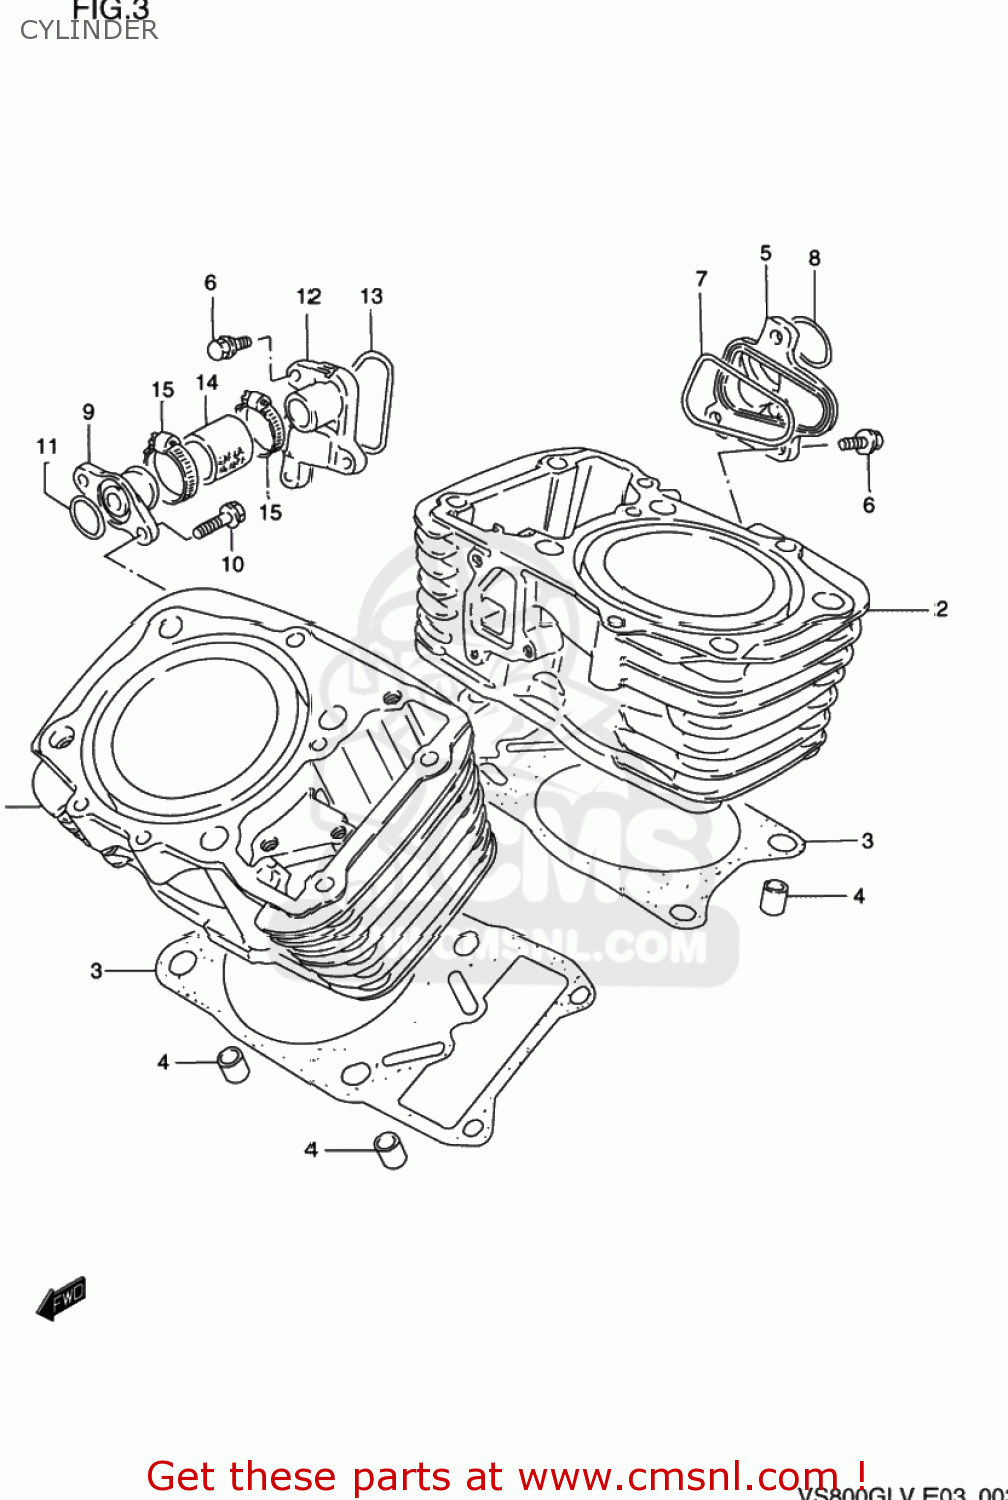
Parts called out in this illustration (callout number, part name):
1	CYLINDER,FR
2	CYLINDER
3	GASKET,CYLINDER (NAS)
4	PIN
5	CHAMBER,WATER,INLET
6	BOLT
7	O RING,INLET WATER CHAMBER
8	O RING(D:2.3,ID:24.4)
9	UNION,WATER INLET
10	BOLT
11	O RING(D:2.4,ID:15.8)
12	CHAMBER,WATER,OUTLET
13	O RING,OUTLET WATER CHAMBER
14	HOSE,RADIATOR
15	CLAMP
